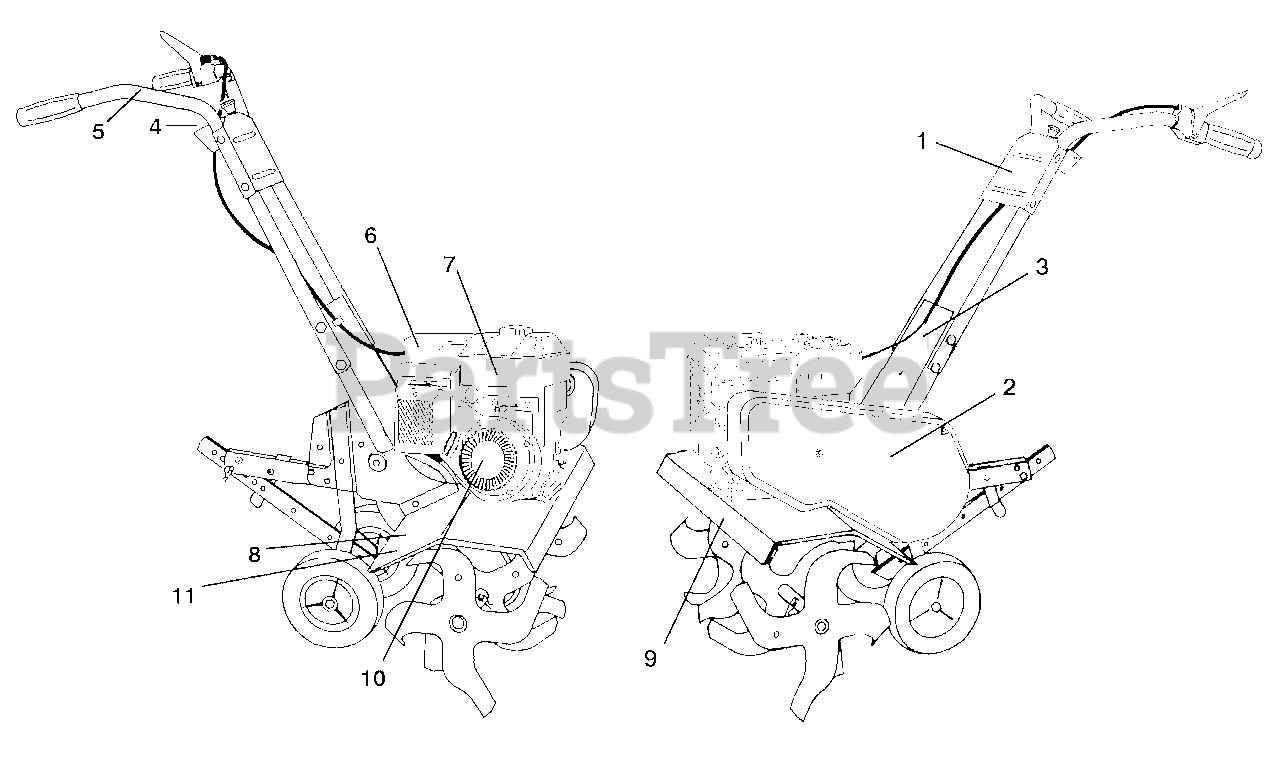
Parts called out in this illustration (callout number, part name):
1	Decal, Poulan
2	Decal, Poulan, 825 Series / 26"
3	Decal, Forward and Reverse
4	Decal, Reverse, Tine Control
5	Decal, Hand Placement
6	Decal, Engine
7	Decal, OHV, I/C
8	Decal, Warning
9	Decal, Heavy Duty
10	Decal, Rewind Starter
11	Decal, Warning, Rotating Tines
11	Manual, Operator's, English / French
11	Manual, Repair Parts
